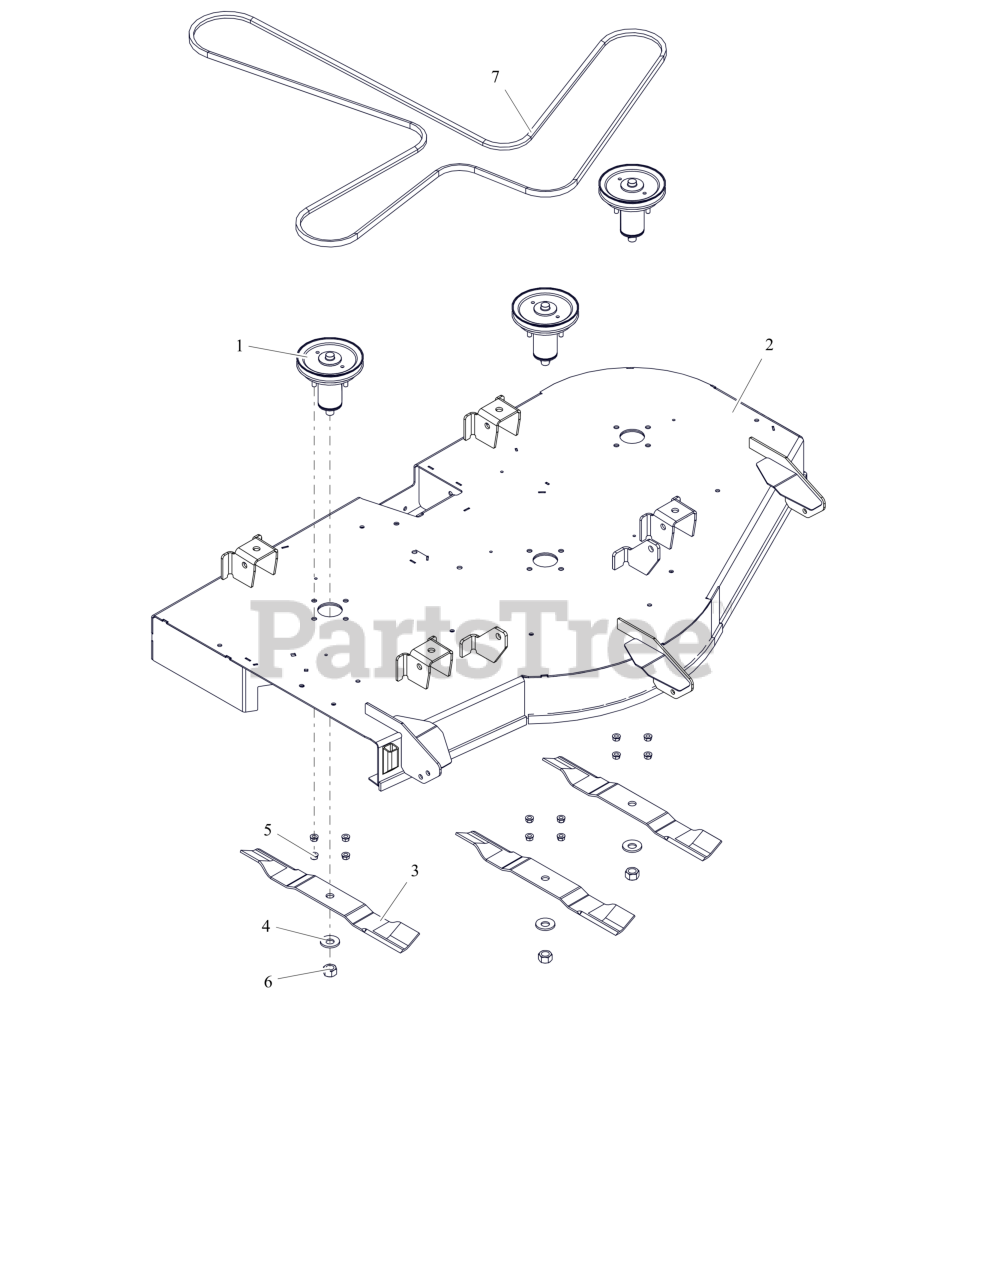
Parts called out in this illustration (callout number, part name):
1	KIT- DECK SPINDLE ASSM- 52"
2	WLDMT, DECK 52" (GREY)
3	BLADE, 18" - 30 DEG .5 OFFSET
4	WSHR-BLVL .669X1.535X.138
5	NUT,LK-CTR-FLG .31-18 GF ZCC
6	NUT-STD .625-18 ZCC
7	V-BELT, HA-WRAPPED
